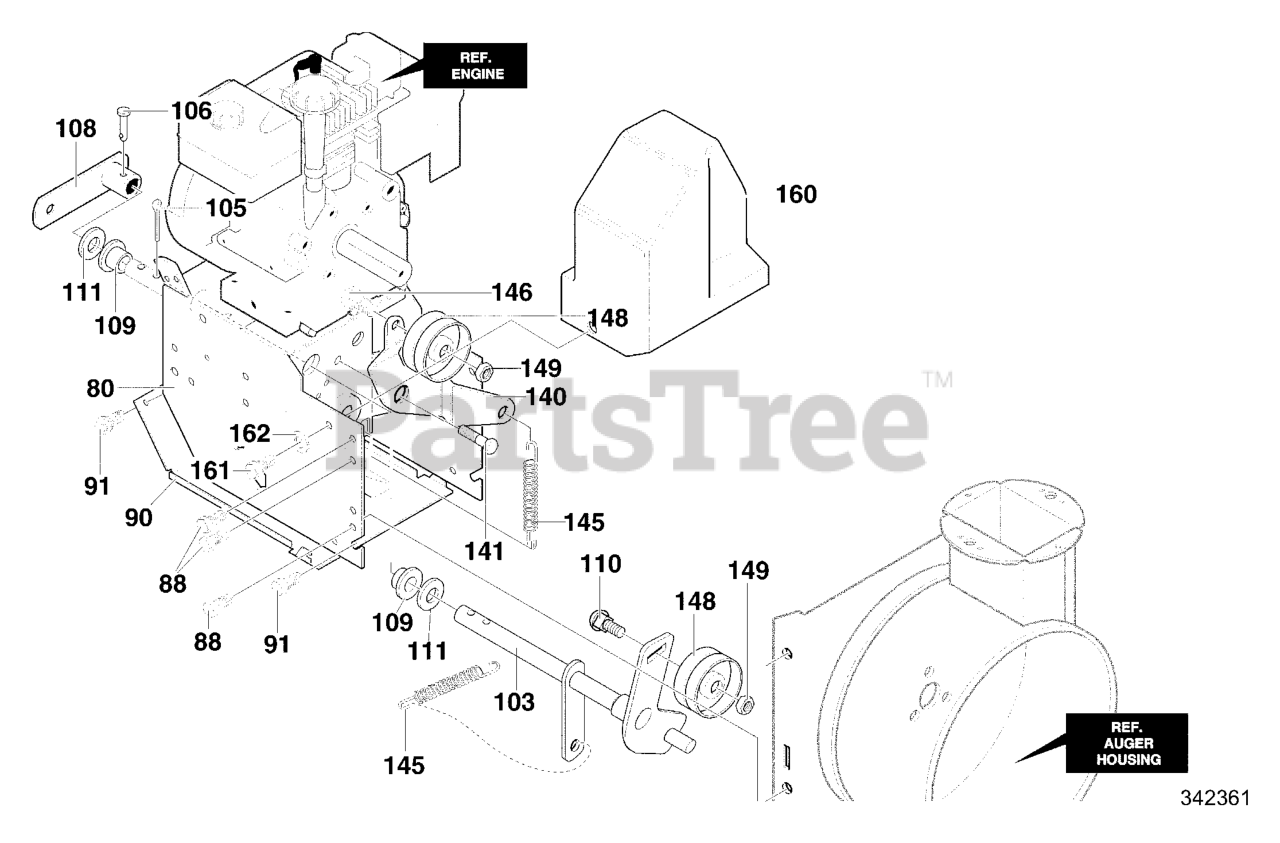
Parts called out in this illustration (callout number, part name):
80	FRAME ASSY
88	SCREW, 5/16-18 x 0.50
90	COVER, BOTTOM
91	SCREW, 1/4-20X .63
103	IDLER ASSEMBLY
105	PIN, HAIR
106	PIN, KLIK 3/16"
108	ASSY., SPRING ATTACH WHEEL
109	BEARING, FL.
110	BOLT
111	WASHER, FLAT
140	LEVER, IDLER ARM TRACTION
145	IDLER SPRING TRACTION DRIVE
146	SCREW, 3/8-16 x 1.25
148	PULLEY, IDLER
149	NUT, 3/8-16
160	COVER, BELT
161	SCREW, 1/4-20X .63
162	WASHER, FLAT
